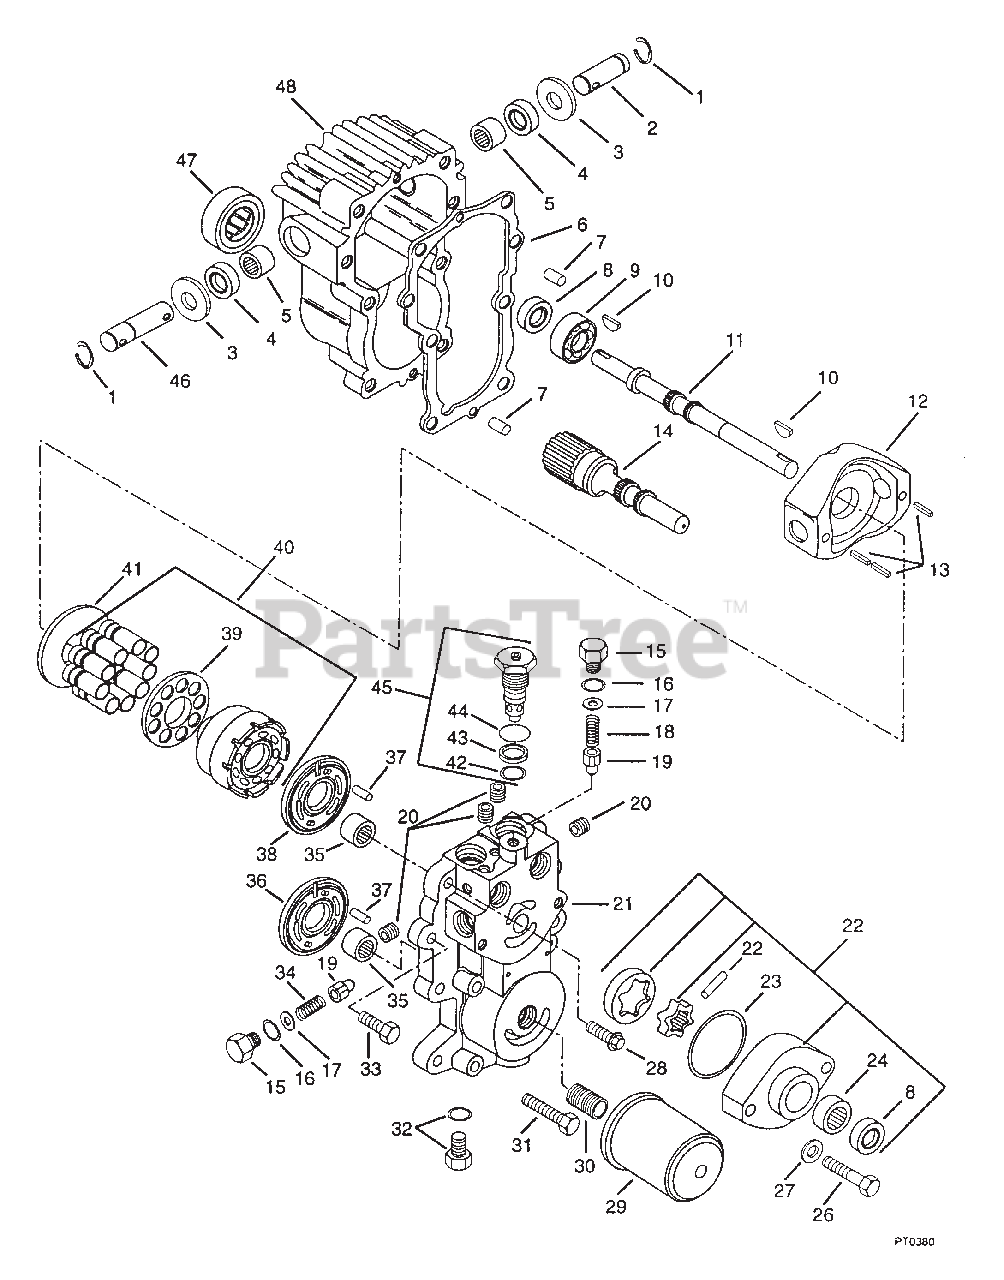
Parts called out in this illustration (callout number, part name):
1	RG-RTNG-EXT .688X.042
2	TRUNNION SHAFT
3	WSHR-FL-STL .699X1.375X.059
4	SEAL .625X1.187X.187
5	BRG-NEEDLE .688X.876X.63
7	DOWEL PIN
8	SEAL .625X1.128X.250
9	BRG-BALL 17MMX40MMX12MM
10	KEY-WDRF .188X.75X.313 SAE 9
11	PUMP SHAFT
12	SWASHPLATE VARIABLE
13	PIN-ROLL .188X.63
14	MOTOR SHAFT
15	PLUG-HEX HEAD
16	O-RING .414X.562X.072
17	SHIM PACKAGE
18	SG-COMP ??X??X?? SUNSTRAND
19	RELIEF VALVE CONE
20	PIPE PLUG
21	CENTER SECTION
23	O-RING 2.364X2.504X.072
24	BRG-NEEDLE .625X.875X.50
25	CHARGE PUMP ASSEMBLY
26	BLT-HEX .44-14X2.00 GR5
27	WSHR-FL-STL .469X.719X.108
28	SCR-12PNT .38-16X1.25 GR5
29	OIL FILTER
31	BLT-HEX .38-16X2.00 PL GR5
32	THREADED PLUG
33	BLT-HEX .38-16X1.50 PL GR5
34	SG-COMP ??X??X?? SUNSTRAND
35	BRG-NEEDLE 17MMX.938X.62
36	MOTOR VALVE PLATE
37	DOWEL PIN
38	VALVE PLATE
39	SLIPPER RETAINER
40	CYLINDER BLOCK KIT
41	THRUST PLATE
42	O-RING .614X.750X.070
43	O-RING .614X.750X.046
44	O-RING .770X.968X.097
45	CHECK VALVE ASSEMBLY
46	TRUNNION SHAFT
47	BRG-ROLLER 1.27X2.05X15MM
48	HOUSING W/SEALS AND BEARINGS
